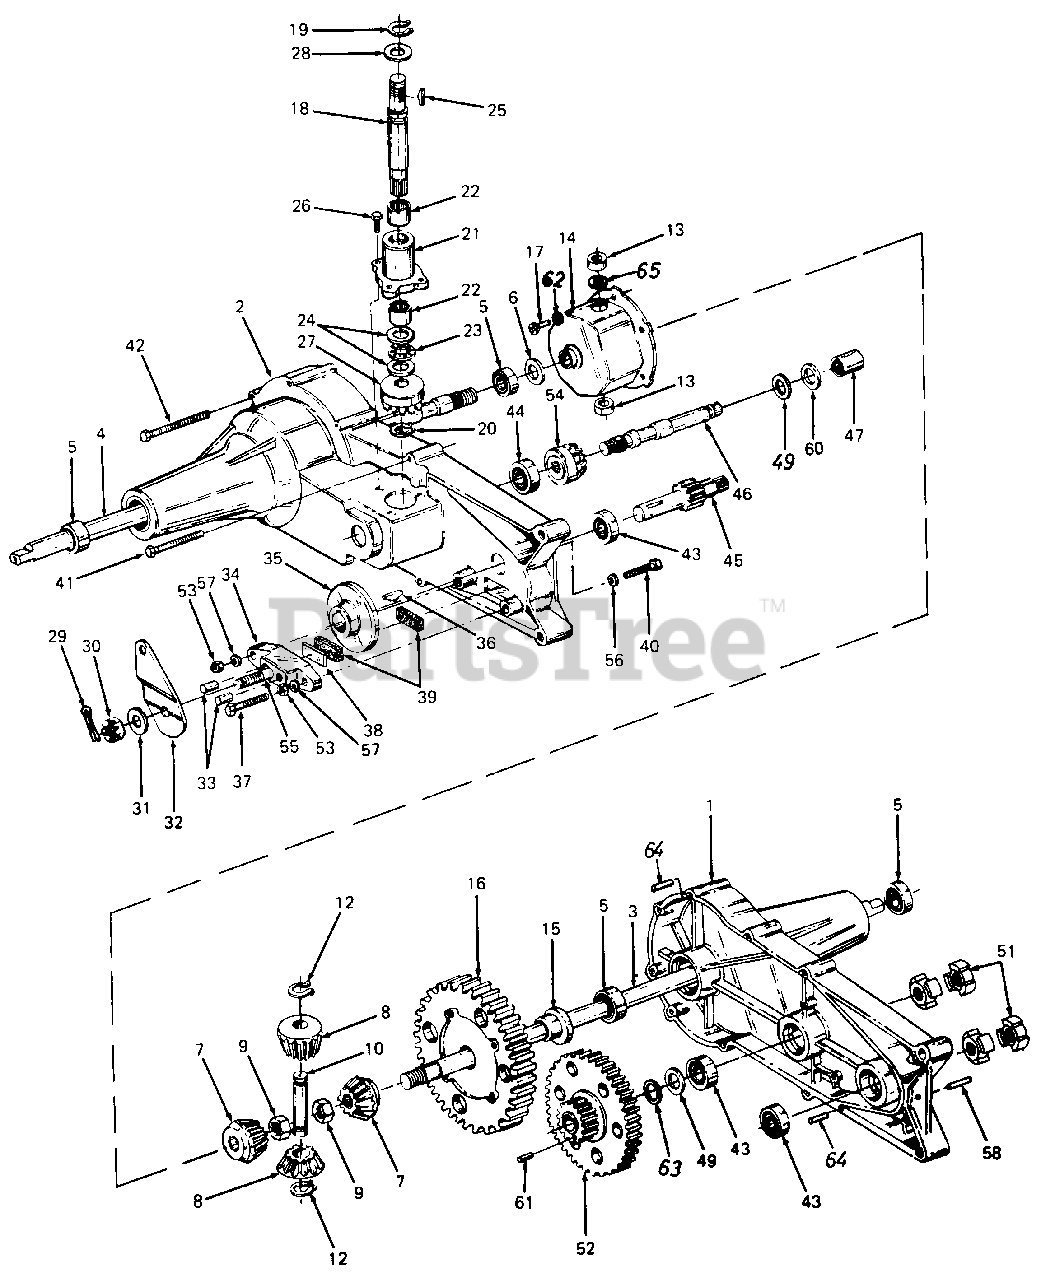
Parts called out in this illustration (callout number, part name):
1	Housing Halt, L.H.
2	Housing Half, R.H.
5	Bearing, Ball
6	Washer, Flat, .76 x 1-1/8" x .306 Thk. Hdn.
7	Gear, Miter
9	Nut, Hex Jam Patch Lock, 1/2-20 0
10	Shaft, Cross
12	Ring, Snap
13	Bearing, Thrust
14	Housing Ass'y. Differential
15	Bearing, Flange, .75 I.D. x .587
16	Gear, Differential, 72 Tooth
17	Bolt,Torx Head 1/4-28 x 5/8" Lg.
18	Shaft, Input
19	Ring, Snap
20	Ring, Retaining, Ext. 7/16 Dia.
21	Bearing, Input Housing
22	Bearing, Needle, 5/8 I.D. x .50 Lg.
23	Bearing, Thrust
24	Washer, Flat, 5/8 I.D. x 1.12 O.D. x .030 Thk.
25	Key #4 Hi-Pro, 3/32 x 5/8 Dia. (Hdn.)
26	Screw, Hex Patch Lock, 1/4-20 X 34 Lg.
27	Gear, Input Pinion, 17 Tooth
28	Washer, Flat, .62 I.D. x 1.0 O.D. x .030 Thk.
30	Nut, Castle, 5/16-24
31	Washer, Flat, .343 x .88 x .062 0 Thk.
32	Arm, Brake Actuator
33	Pin, Actuating, 5/16 Dia.
36	Key, Hi-Pro, 3/16 x 5/8 Dia.
37	Screw, Hex Patch Lock, 20 x 1.5 Lg.
38	Plate, Puck
39	Puck, Brake
40	Screw, Hex Cap, 1/4-20 x 1.5 Lg.
41	Screw, Hex Self-Tap, 1/4-20 x 2.0 Lg.
42	Screw, Hex Self-Tap, 1/4-20 x 2.75 Lg.
43	Bearing, Ball
44	Bearing, Ball
45	Shaft Pinion w/11 Tooth Gear
46	Shaft Drive
47	Bearing, Needle
49	Washer, Flat, 5/8 x 1.12 x .060 Thk.
51	Couping
52	Gear, Tooth 60 & 17
53	Nut, Hex Jam, 1/4-20
54	Gear, Drive Pinion, 17 Tooth
55	Bolt, Square Hd. 5/16-24
56	Washer, Flat, .265 x .938 x .12 Thk.
57	Washer, Lock, 1/4
58	Pin, Roil, 3/16 Dia. x .50 Lg.
60	Bronze Thrust Brg. 5/8" I.D.
61	Dowel Pin 3/32" x 1/4"
62	Washer, HD. Spring Lock 1/4"
63	Seal, Grease
64	Pin Roll 3/16" Dia.
65	Washer, Flat .62" I.D. x 1.0" O.D. x .20" Thk.
